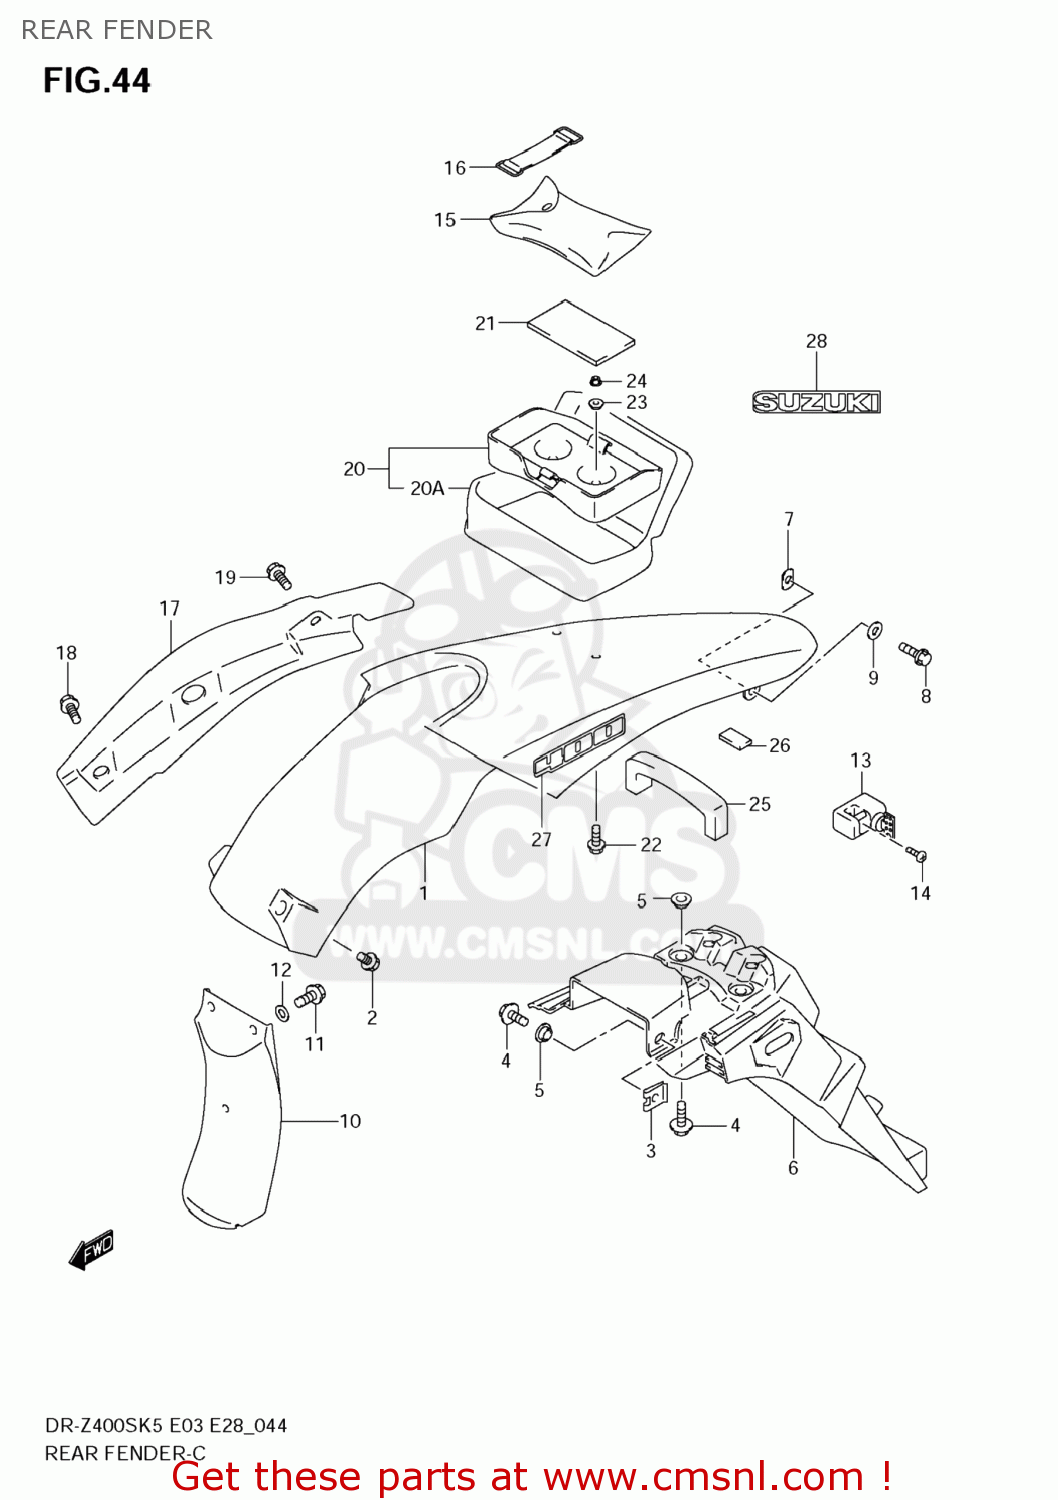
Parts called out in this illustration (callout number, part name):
1	FENDER,RR
2	BOLT(6X16)
3	PLATE,RR FENDER
4	BOLT(6X20)
5	WASHER
6	EXTENSION,RR FENDER
7	NUT,COWL
8	BOLT
9	WASHER
10	MUDGUARD,RR FENDER FR
11	BOLT
12	WASHER
13	LOCK SET,HELMET
14	SCREW(6X14)
15	TOOL ASSY
16	BAND
17	MUDGUARD,RR FENDER,R
18	BOLT(6X18)
19	BOLT
20	BAG ASSY,SEAT TAIL
20A	BAG,SEAT TAIL
21	CUSHION,RR BAG
22	BOLT
23	WASHER
24	NUT
25	SEALER,SIDE COVER L
26	PROTECTOR(170X95X3.0)
27	EMBLEM,RR FENDER
28	EMBLEM,SUZUKI
